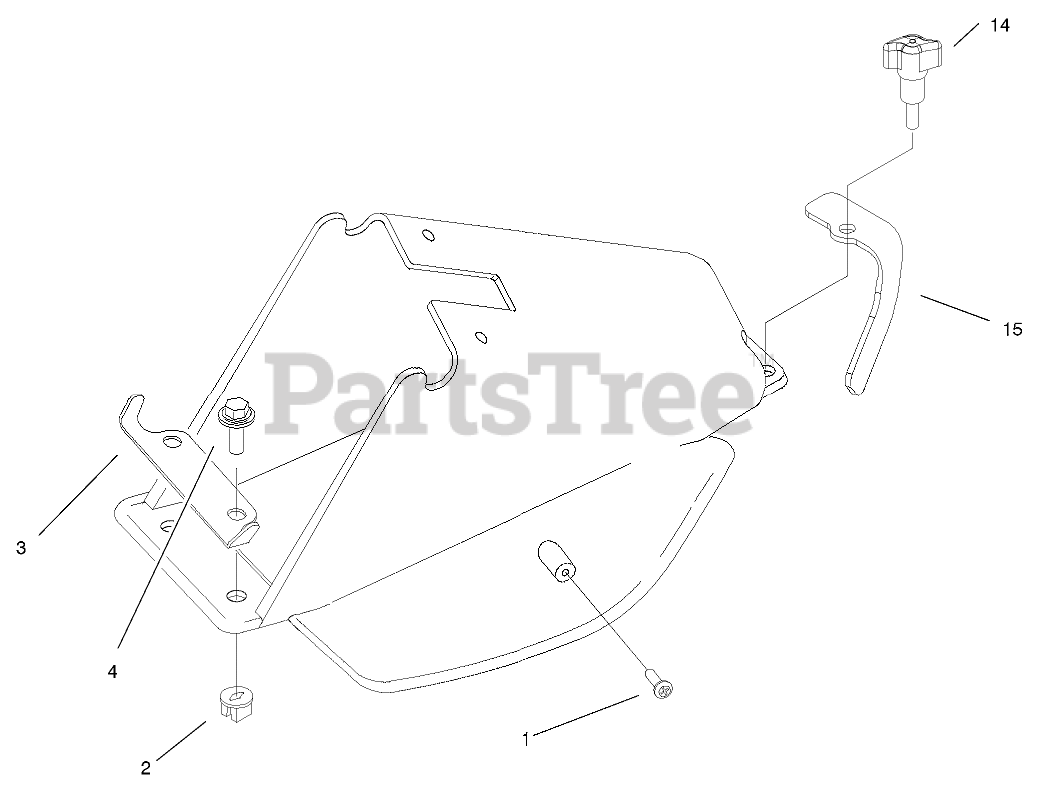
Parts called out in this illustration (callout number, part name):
1	Screw-PPH (only on: 20023, 20023c)
2	Grommet (only on: 20023, 20023c)
3	Bracket-Mount,Chute (only on: 20023, 20023c)
4	Screw-HWH (only on: 20023, 20023c)
14	Knob (only on: 20023, 20023c)
15	Clamp-Door (only on: 20023, 20023c)
